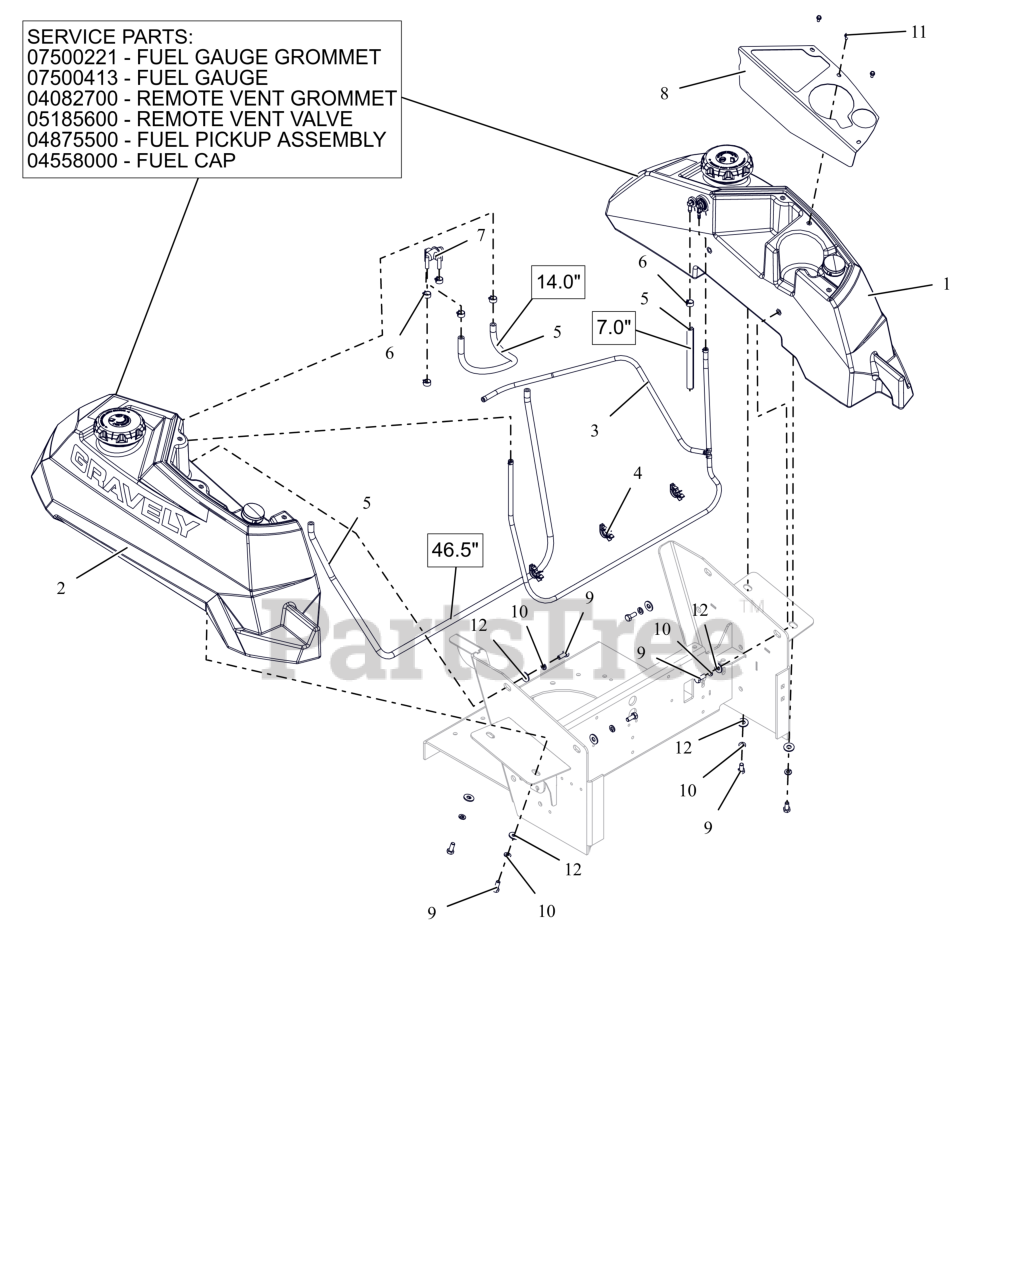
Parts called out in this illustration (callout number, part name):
1	ASM, LH - PT100 FUEL TANK
1	GROMMET, FUEL GAUGE
1	GAUGE, REMOTE SEALED FUEL
1	GROMMET, REMOTE VENT NITRILE
1	VALVE, COMBINATION VENT 3/16
1	ASSM,LRG TANK FUEL PICKUP LINE
1	CAP, FUEL VENTIN AUTOLOCK
2	ASM, RH - PT100 FUEL TANK
2	GROMMET, FUEL GAUGE
2	GAUGE, REMOTE SEALED FUEL
2	GROMMET, REMOTE VENT NITRILE
2	VALVE, COMBINATION VENT 3/16
2	ASSM,LRG TANK FUEL PICKUP LINE
2	CAP, FUEL VENTIN AUTOLOCK
3	ASM, VAPOR LINE
4	WIRE CLIP
5	HOSE, .25 LOW-PERM BULK GAS
6	CLAMP, FUEL LINE
7	VALVE, FUEL
8	PT100 CUPHOLDER PANEL - RED
9	BLT,HEX .31-18X.75 G5 ZCC
10	WSHR,LK-REG .312X.078 ZCC
11	SCR-MCH 10-24X.38 HWHSTAINLESS
12	WSHR,FLT .375X.875X.083 ZCC
